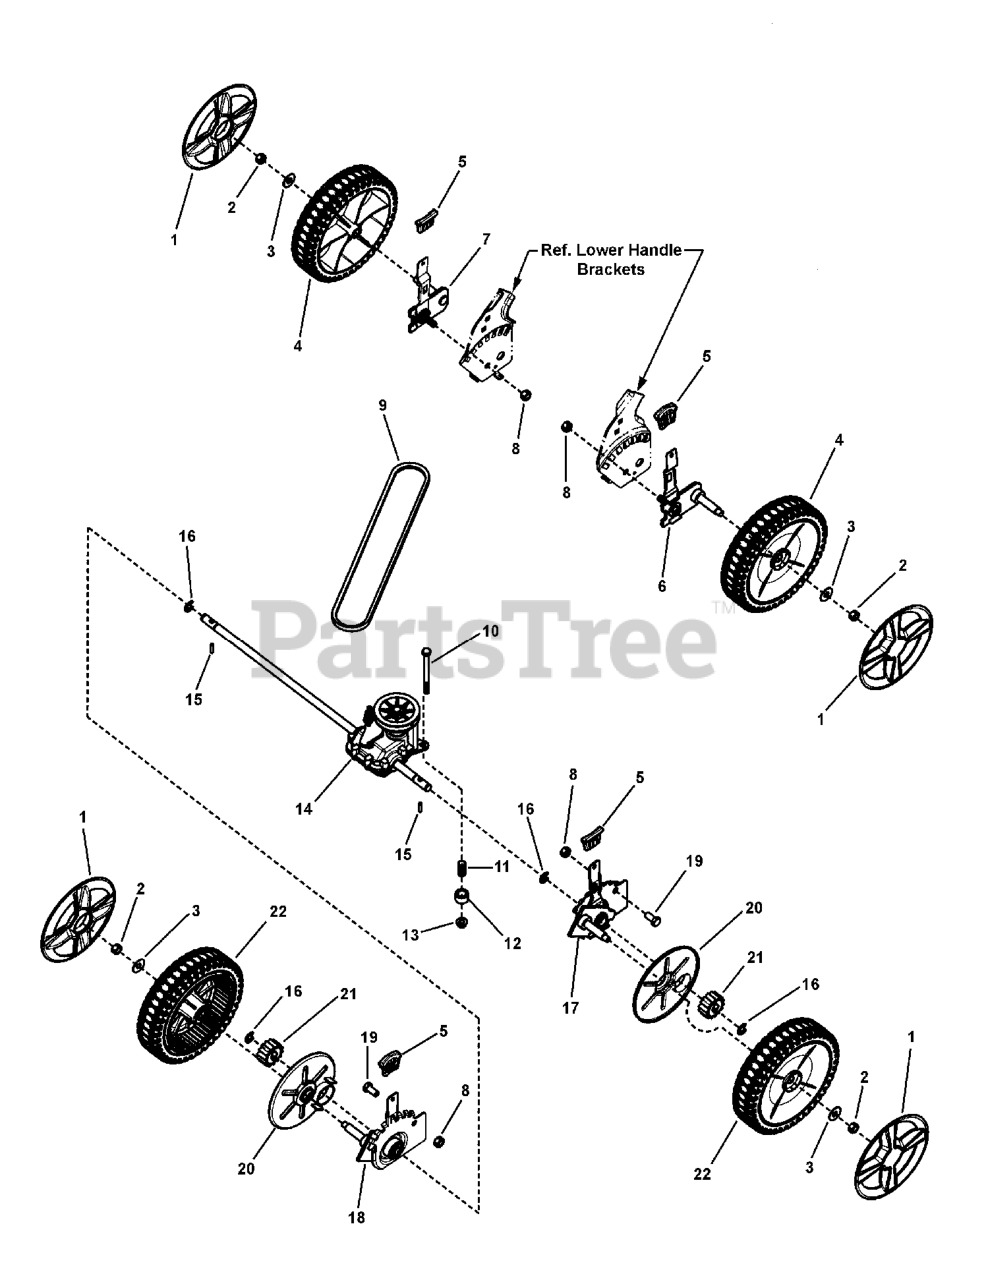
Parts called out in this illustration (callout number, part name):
1	HUBCAP, 8"& 9" Wheel Spoked, P-391 St Yellow
2	NUT, 3/8-16 Hex Center Lock, YZ
3	WASHER, 1" OD x .387 ID Flat
4	WHEEL, 8" X 2" Idle w/Db Tread, Brute, Satin Black
5	GRIP, Height Latch, P-391-St, Yellow
6	KIT, LR, Height-Of-Cut, 22" WBM 2N1
7	KIT, RR, Height-Of-Cut, 22" WBM 2N1
8	NUT, 3/8-16, Hex Flange Lock GR 5
9	BELT, Drive 22" WBM Single Speed
10	SCREW, 5/16-18 x 3-3/4" Hex Head Cap, GR 5
11	SPRING, Compression
12	SPACER, Drive Transmission
13	NUT, 5/16-18 Hex Flange Lock
14	TRANSMISSION, 22" WBM Single Speed, Front Wheel Drive
15	PIN, Drive, 22" WBM, Front Wheel Drive
16	RETAINING RING
17	KIT, LF, Height-Of-Cut, Front Wheel Drive, 2N1
18	KIT, RF, Height-Of-Cut, Front Wheel Drive, 2N1
19	BOLT, 3/8-16 x 3/4" Hex Head, GR 5
20	SHIELD, Dust, 22" WBM, Front Wheel Drive
21	GEAR, Pinion, 22" WBM, Front Wheel Drive
22	WHEEL, 8" x 2" Drive, w/DB Tread P-290 Satin Black
